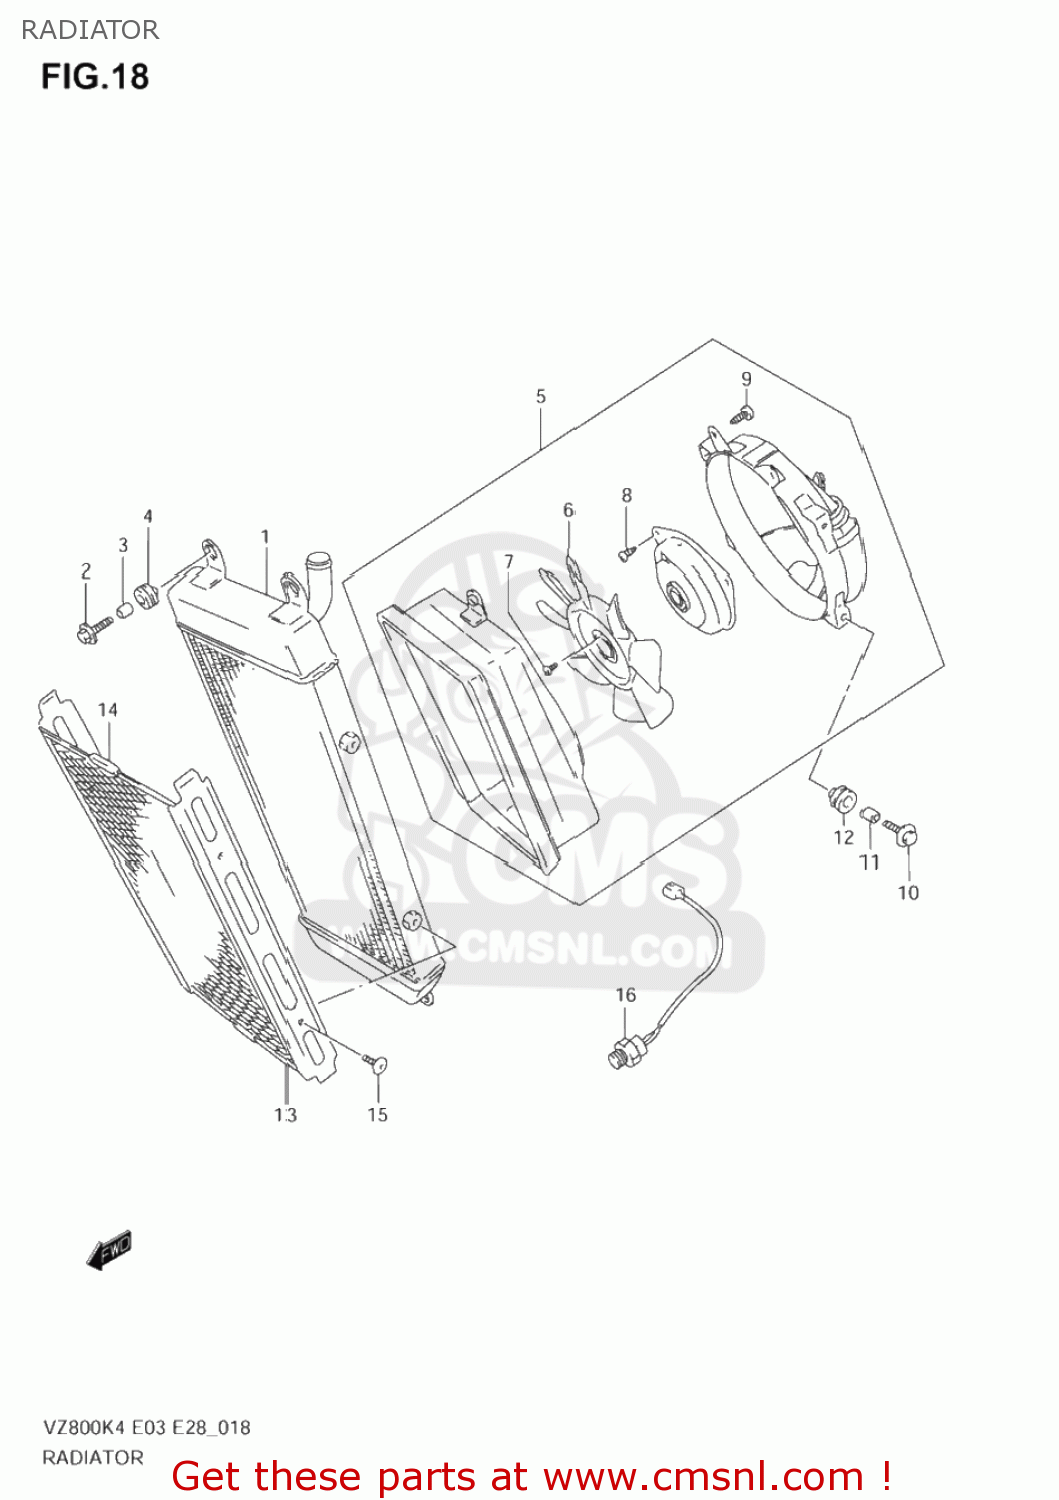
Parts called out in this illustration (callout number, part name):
1	RADIATOR ASSY,WATER
2	BOLT(6X20)
3	SPACER(6.5X10X10)
4	CUSHION
5	FAN ASSY,RADIATOR
6	FAN
7	SCREW 4X6
8	SCREW
9	SCREW 5X12
10	BOLT(6X20)
11	SPACER(6.5X10X10)
12	CUSHION
13	COVER,RADIATOR
14	PROTECTOR,CTR
15	SCREW(6X10)
16	SWITCH ASSY,WATER TEMP
